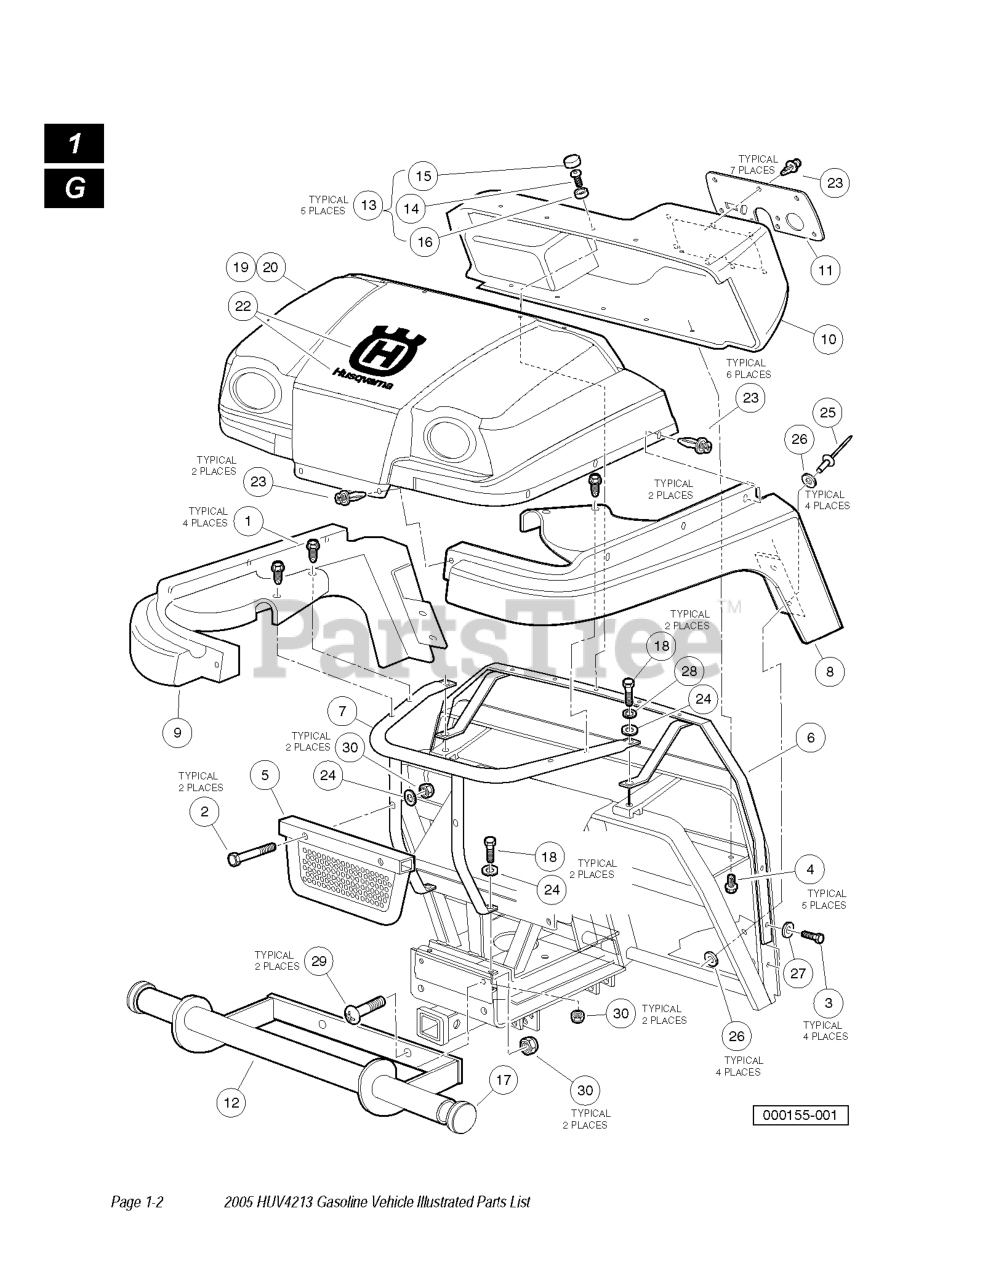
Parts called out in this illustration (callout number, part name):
1	SCREW, HEX WASH
2	SCREW HEX CAP
3	SCREW HX TYP TT
4	SCREW, #12 X .50 TYP AB HX WSH
5	GRILL ASSY
6	SUPPORT, UPPER COWL
7	SUPPORT, LOWER FENDER
8	FENDER, LEFT FRONT
9	FENDER, RIGHT FRONT
10	DASH BOARD
11	PANEL, DASH
12	BUMPER ASSEMBLY
13	KIT - DASH HDWR
14	SCREW 1/4-20X.75 TORX PN HD
15	CAP 1/4" PLASTIC SCREW HEAD
16	WASHER 1/4 ID SCALLOPED PLAST
18	SCREW, 5/16-18 X 2.50 HEX CAP
19	Cowl, Camo
20	COWL, OEM 1299, ORANGE
21	FLOORMAT, MOLDED -UTL
22	DECAL HOOD
23	SCREW, TUFLOK PANEL, 1/4
24	WASHER, 5/16 TYPE A FLAT
25	RIVET, 3/16 X .5 ALUM POP
26	WASHER FLAT
27	WASHER 1/4 FLAT
28	LOCKWASHER, 5/16 SPLIT
29	SCREW 5/16-18 X 1.25 TRUSS HD
30	LOCKNUT, 5/16-18 NYLON INSERT
